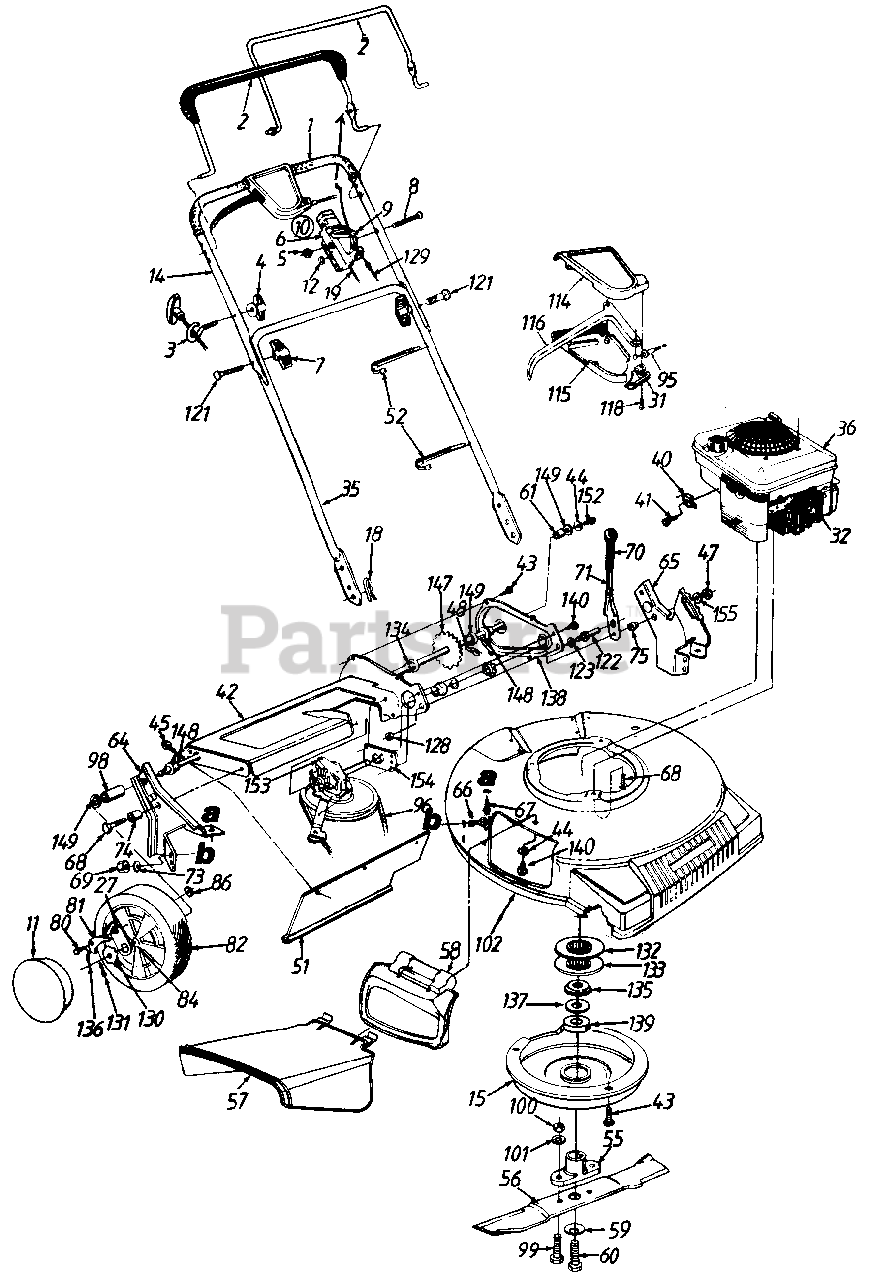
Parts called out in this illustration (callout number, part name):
1	Grip
2	Control Handle w/Plastic
3	Rope Guide
4	Handle Knob 1/4-20 Thd.
5	Hex L-Nut 1/4-20 Thd.
6	Throttle Body
7	Hand Knob
8	Oval C-Sunk Scr.
9	Throttle Lever
10	Throttle Box Comp.
11	Hub Cap
12	Spr. Wash. .66" I.D.
19	Throttle Control Wire 55" Lg.
27	Pawl Plate
31	S.P. Control Cover
32	Spark Plug Insulator
36	Engine
40	Cable Clamp
41	Hex Self-Tap Scr. #10-32 x .62
44	Bell-Wash. 1/4" I.D.
45	Hex AB-Tap Scr. 1/4 x .62
47	Hex Patch L-Nut 3/8-24 Thd.
48	#48 Chain .500" Pitch x 38 Links
51	Rear Flap 4.8" x 17.5" Lg.
52	Cable Tie
55	Blade Adapter
56	21" Mulching Blade
57	Chute Ass'y.
58	Mulching Plug Ass'y.
59	Bell-Wash. .39" I.D.
60	Hex Bolt 3/8-24 x 2.5"
61	Spacer .513" I.D.
67	Hex B-Tap Scr. 5/16-18
68	Hex TT-Tap Scr. 3/8-16
69	Hex Nut 5/16-18 Thd.
71	Height Adj. Lever
73	Bell-Wash. 5/16" I.D.
74	Spacer .383" I.D.
75	Shld. Spacer .5" Dia.
80	Shld. Scr. .342" Dia. x .268
81	Pawl - R.H.
82	Wheel Ass'y. Comp. - Rear
84	Sleeve Bearing 1/2" I.D.
86	Weld Top L-Nut 1/4-20 Thd.
95	S.P. Cable - 44" Lg.
96	"V"-Belt
98	Sleeve .526" I.D.
99	Hex Bolt 3/8-24 x 1.0" Lg.
100	Hex Nut 3/8-24 Thd.
101	L-Wash. 3/8" I.D.
115	Self-Propelled Control Cover
116	Control Lever
118	Fl - "C"-Sunk Hd. Tap Scr. #18 x .75" Lg.
121	Curved Hd. Bolt 5/16-18 x 2" Lg.
122	Shld. Pin 1.43" Lg.
123	L-Wash. 3/8" I.D.
128	Hex Jam Nut 3/8-24 Thd.
129	Control Cable - 39"
130	Ratchet Wheel 1.62" O.D.
131	Cotter Pin 1/8" Dia. x 1"
132	Pulley Half
133	Pulley Half
134	Hex Flange Bearing
135	Spr. Wash. .89" I.D.
136	Spring - Nylon
137	Fl - Wash. .85" I.D.
140	Hex S-Tap Scr. 1/4-20 x .50"
147	Rear Shaft Ass'y. 21.44" Lg.
148	Hex Flange Brg. .506" I.D.
149	Fl - Wash. .531" I.D. x .930"
152	Hex Bolt 1/4-20 x .62" Lg. (Grade 5)
153	Transmission Comp. (See Breakdown)
155	Fl - Wash. .385" I.D. x .87" O.D.
